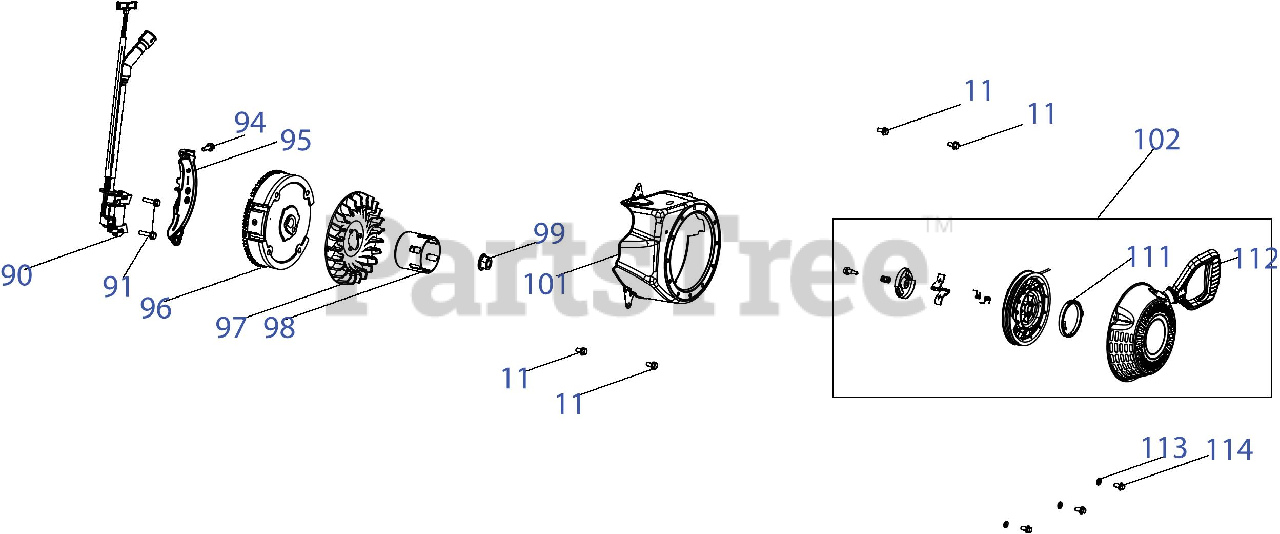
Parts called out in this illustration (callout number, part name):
11	Bolt, M6?12
90	Ignition Module
91	Bolt, M6?25
94	Bolt, M6?20
95	Lower Shield
97	Cooling Fan
98	Starter Cup
99	Nut, M14?1.5
101	Blower Housing
102	Recoil Starter
111	Recoil Spring
112	Starter Handle
113	Washer, 6
114	Bolt, M6?12
